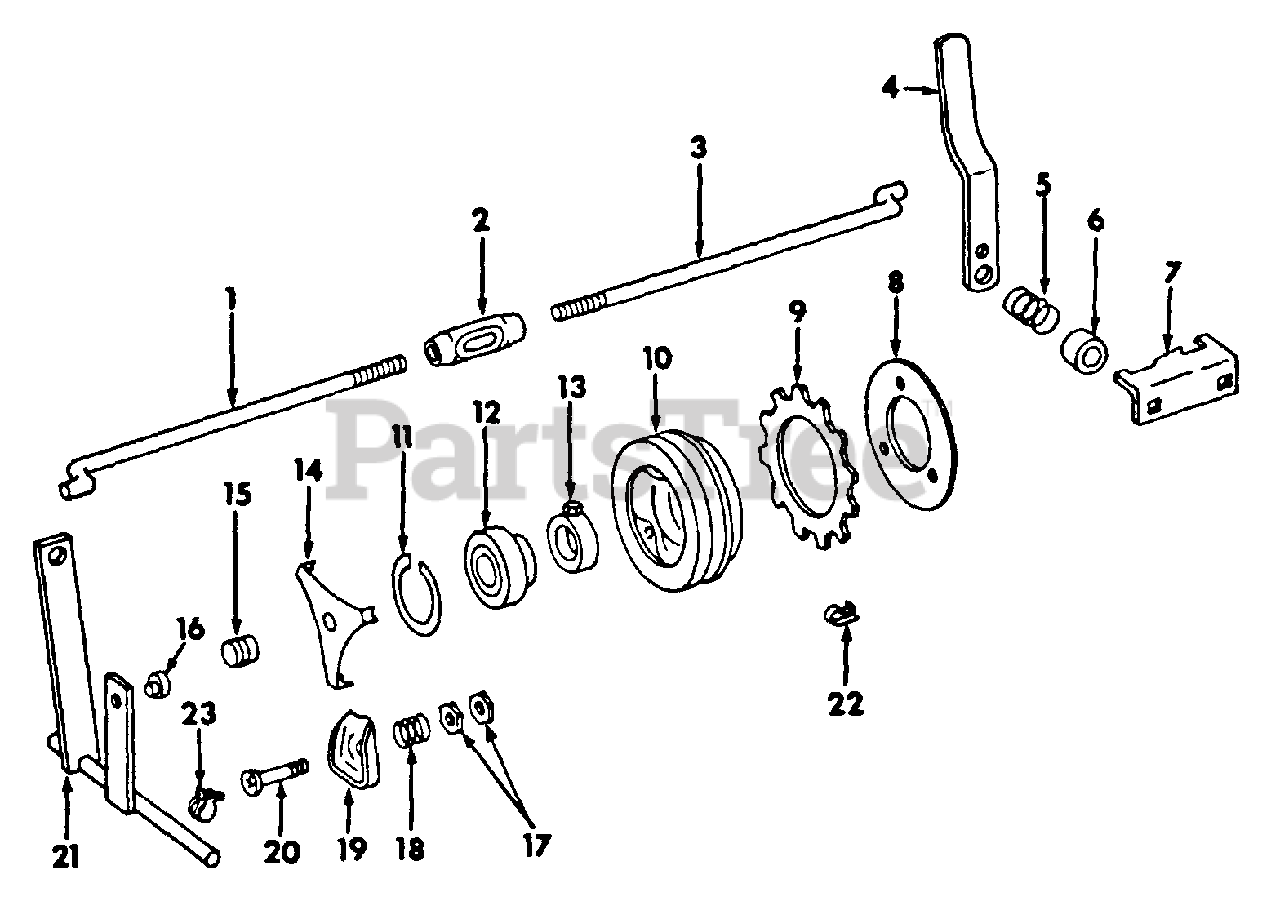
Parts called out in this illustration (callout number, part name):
2	TURNBUCKLE, ROD
3	ROD, REAR CLUTCH
4	LEVER, HANDLE-WILL WORK FOR 473485-R2
5	SPRING. 15 GA COMPRESSION
6	SPACER, SPRING
7	LATCH, HANDLE
8	PLATE, PRESSURE
10	PULLEY, MOWER ACTUATING
11	RING, SNAP 2.197 O.D., FOR PULLEY
12	BEARING W/SNAP RING, BALL
13	COLLAR W/SET SCREW & LOCK NUT, BRG
14	SPRING, PRESSURE
15	BUTTON, THRUST
16	BUTTON, WEAR
17	NUT, 1/4-28 HEX. JAM
18	SPRING, COMPRESSION
19	LEVER, THROW-OUT
20	SCREW, SPECIAL MACHINE
21	SHAFT W/BUTTON, P/N 478483-R1, CLUTCH
22	SPRING, FRICTION DISC
23	CLAMP, LOCATING
